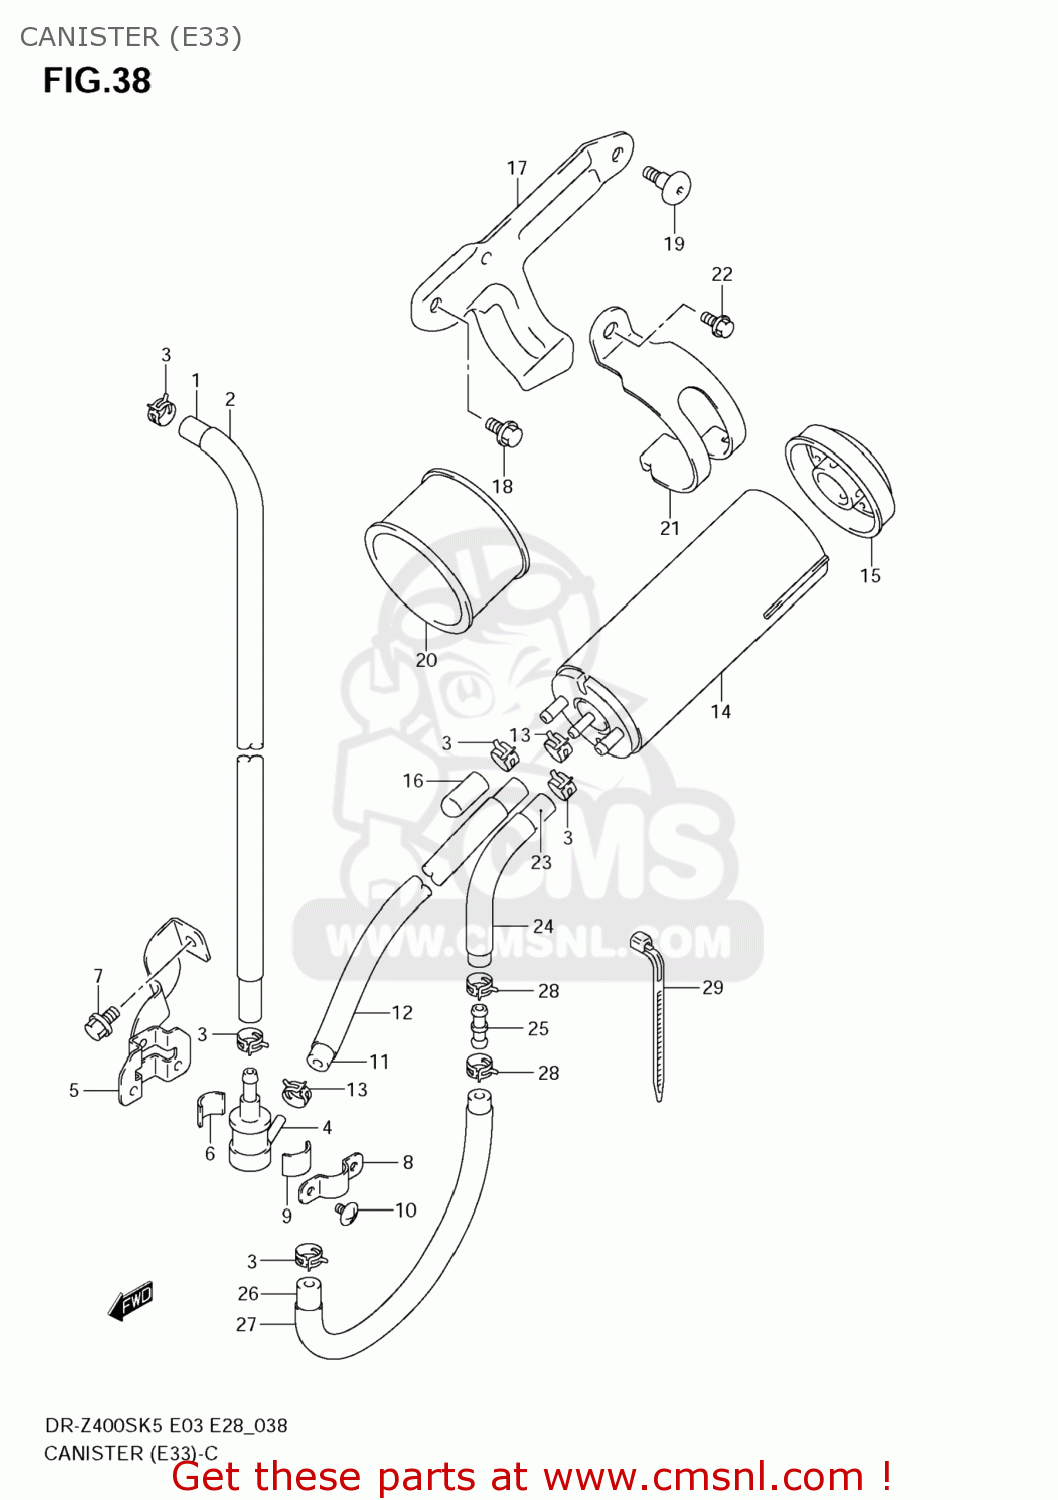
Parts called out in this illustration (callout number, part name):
1	HOSE,TANK & BREATHER VALVE
2	PROTECTOR(14.5X15.5X600)
3	CLIP
4	VALVE,FUEL TANK BREATHER
5	BRACKET,BREATHER VALVE
6	CUSHION
7	BOLT
8	PLATE,FUEL TANK BREATHER NO.2
9	CUSHION
10	SCREW
11	HOSE,BREATHER VALVE & CANISTER
12	HOSE
13	CLIP
14	CANISTER ASSY,CHARCOAL
15	CAP,CANISTER
16	CAP,OD:11.5
17	BRACKET,CANISTER
18	BOLT
19	BOLT(6X16)
20	CUSHION,CANISTER
21	HOLDER,CANISTER
22	BOLT
23	HOSE,CSTR PURGE
24	PROTECTOR(14.5X15.5X600)
25	UNION
26	HOSE,CSTR & CARB PURGE NO.2
27	PROTECTOR(14.5X15.5X600)
28	CLIP
29	CLAMP(L:145)
